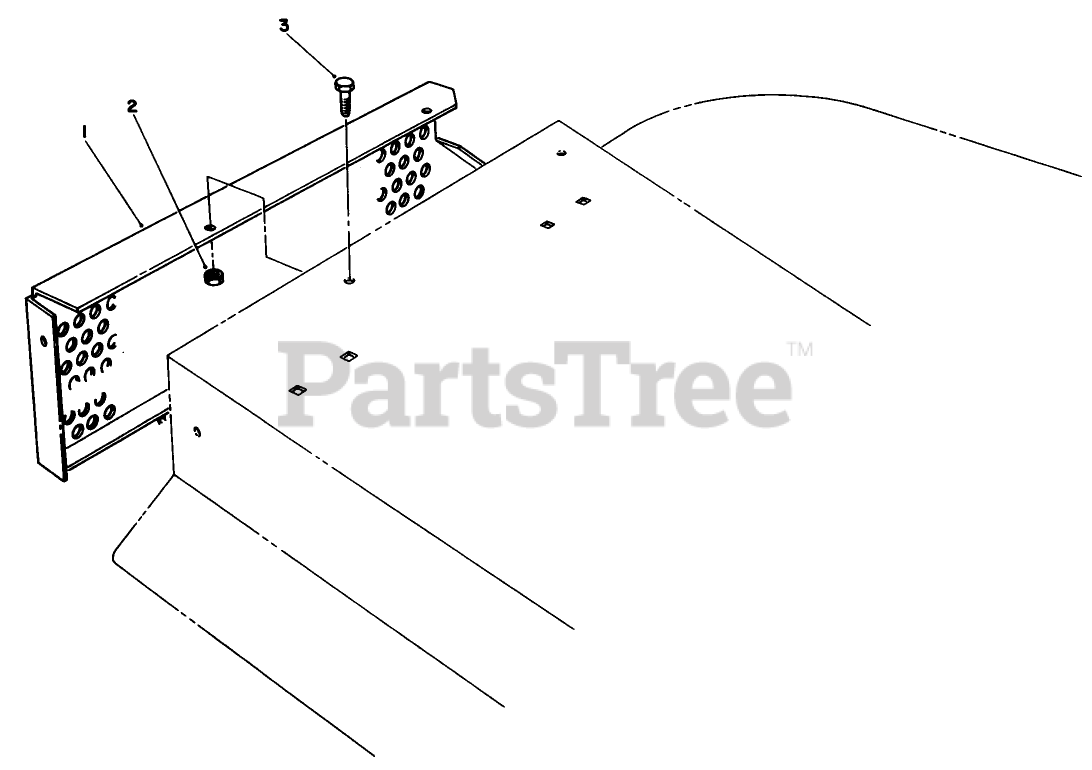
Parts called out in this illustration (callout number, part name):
1	Plate-Mulcher
2	NUT-HF
3	SCREW-HH
